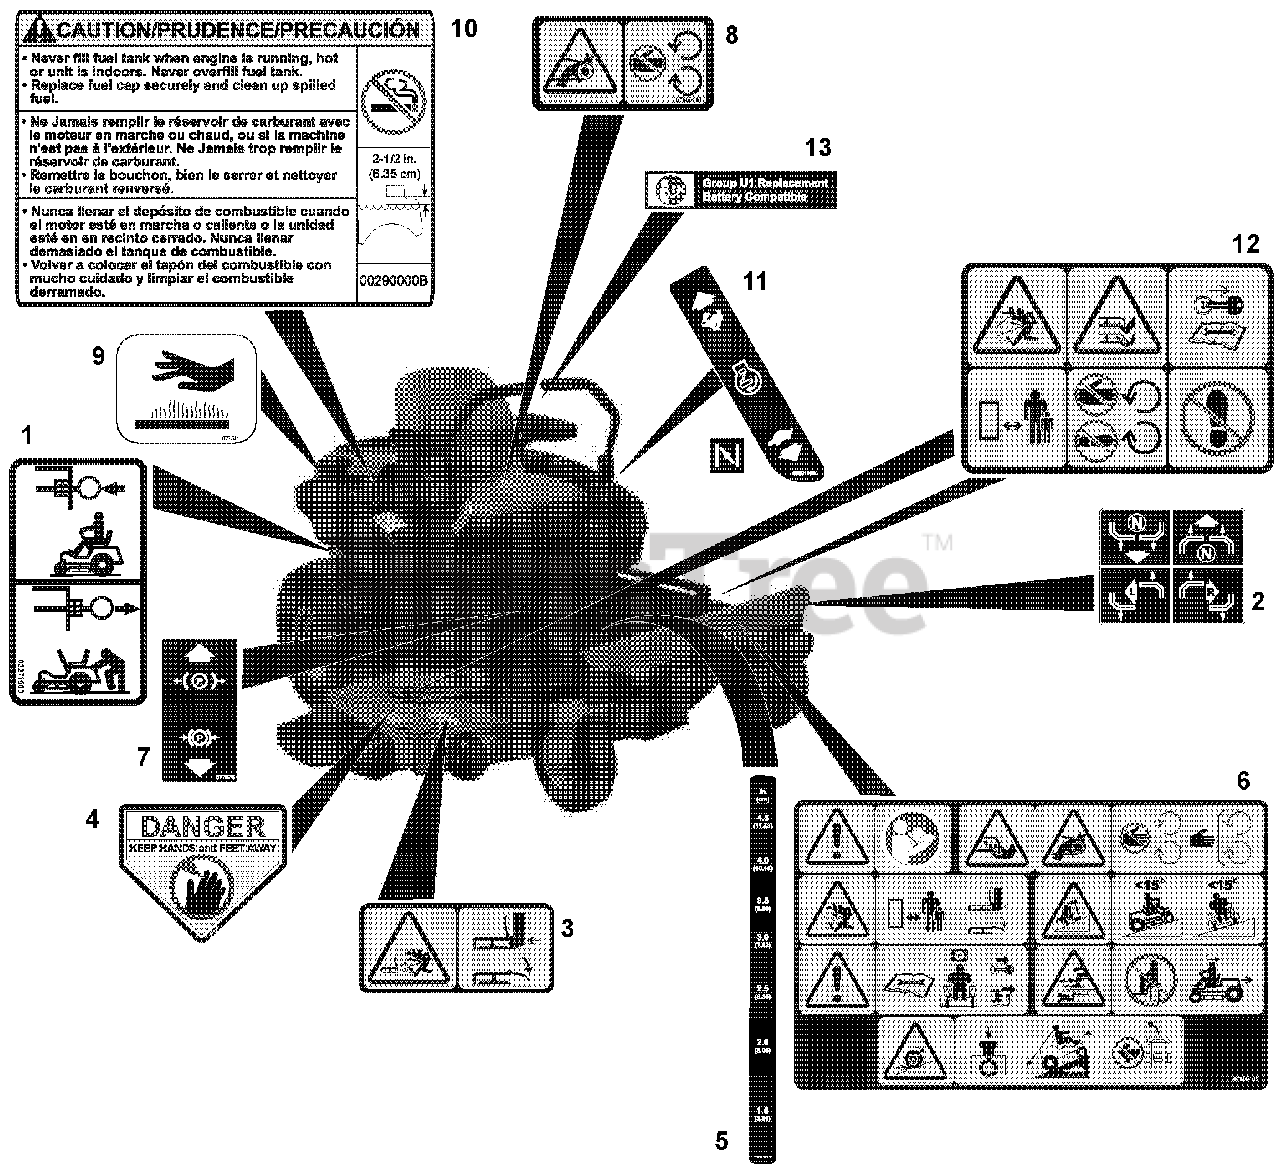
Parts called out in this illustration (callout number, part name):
1	DECAL, TRANSMISSION DISCONNECT
2	DECAL, INSTRUCTIONAL-STEERING
3	DECAL, SAFETY - DECK GUARDING
4	DECAL, DANGER
5	DECAL, CUT HEIGHT XL
6	DECAL, MAIN SAFETY
7	DECAL, PARKING BRAKE LEVER
8	DECAL, SAFETY - GUARDING
9	DECAL, HOT SURFACE
10	DECAL,FUEL WARNING
11	DECAL, SPEED CONTROL
12	DECAL, SAFETY - MOWER DECK
13	DECAL, U1 BATTERY REPLACEMENT
